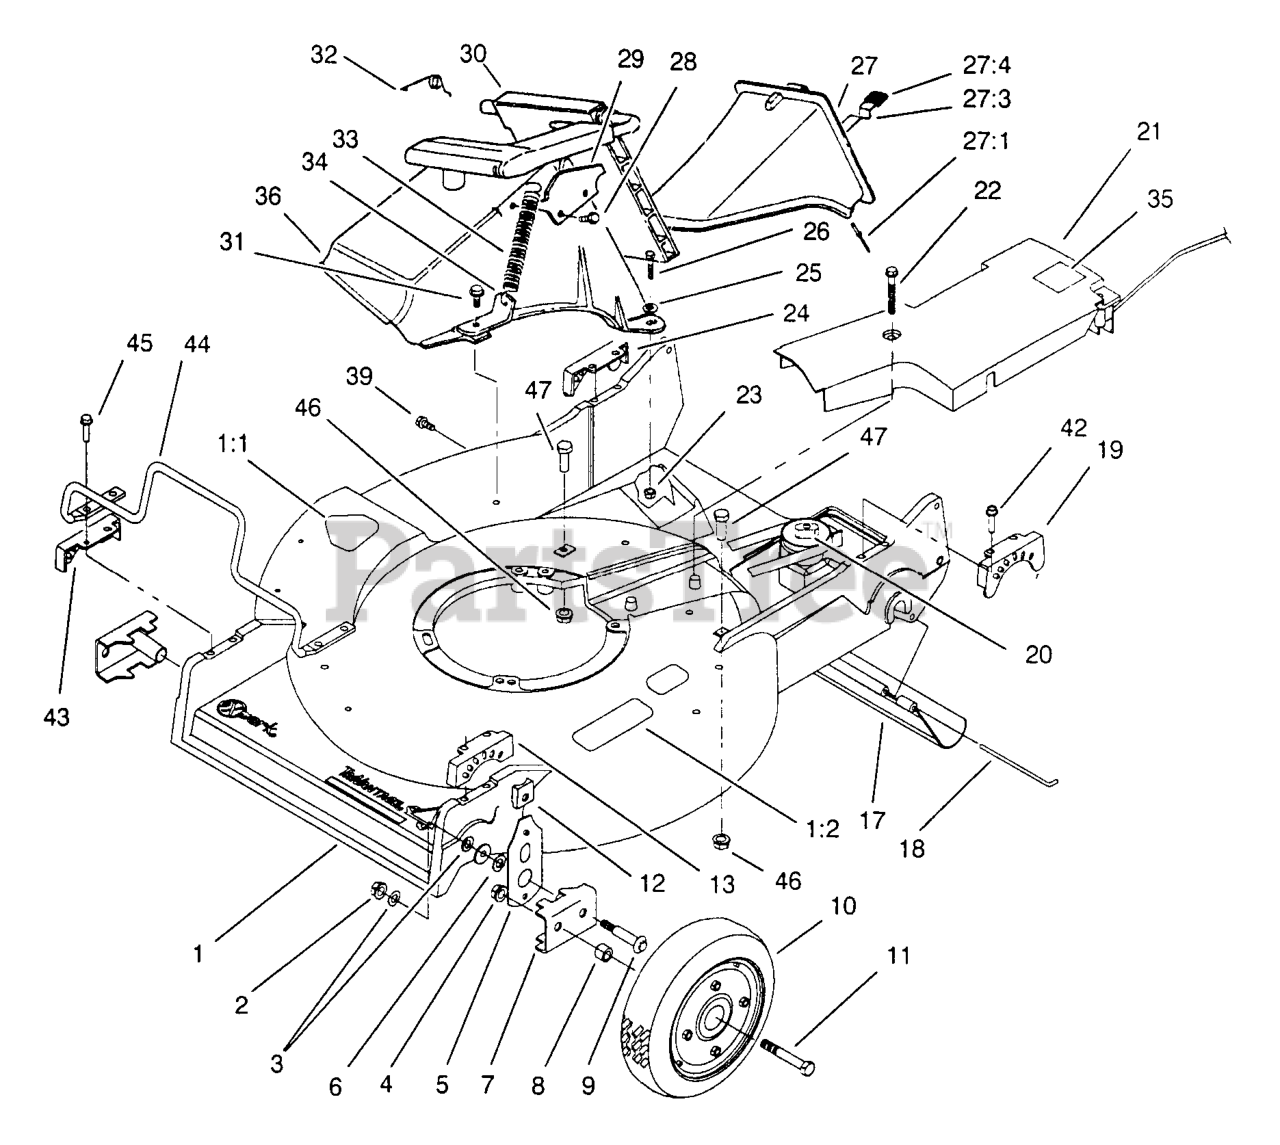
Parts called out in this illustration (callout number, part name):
1:1	DECAL-DANGER
1:2	DECAL-WARNING
2	NUT-LOCK
4	NUT-LOCK, CONE
5	FRONT SPRING ARM ASM
6	WASHER-THRUST
7	ARM-PIVOT, FRONT
8	SPACER-WHEEL
11	BOLT-CARR
12	KNOB-ARM
13	QUADRANT-FRONT, LH
18	ROD-SHIELD
19	QUADRANT-REAR, LH
21	COVER-BELT
22	SCREW-HWH
23	NUT-LOCK, NI
24	QUADRANT-REAR, RH
25	WASHER-FLAT
26	SCREW-HH
27	DISCHARGE PLUG ASM
27:1	RIVET-HEAD, FLAT
27:3	LATCH-PLUG, DISCHARGE
27:4	GRIP-LATCH
28	SCREW-PLASTITE
29	LATCH-PLATE
30	DISCHARGE DOOR ASM
31	SCREW-HWH
32	RETAINER-DOOR
33	SPRING-DOOR
34	BRACKET-SPRING
35	Label - Grease
36	TUNNEL-DISCHARGE
39	SCREW AND WASHER ASM
42	SCREW-HWHTF
43	QUADRANT-FRONT, RH
44	GUARD-ENGINE
45	SCREW-HWHTF
46	NUT-LOCK, NI
47	SCREW-HH
